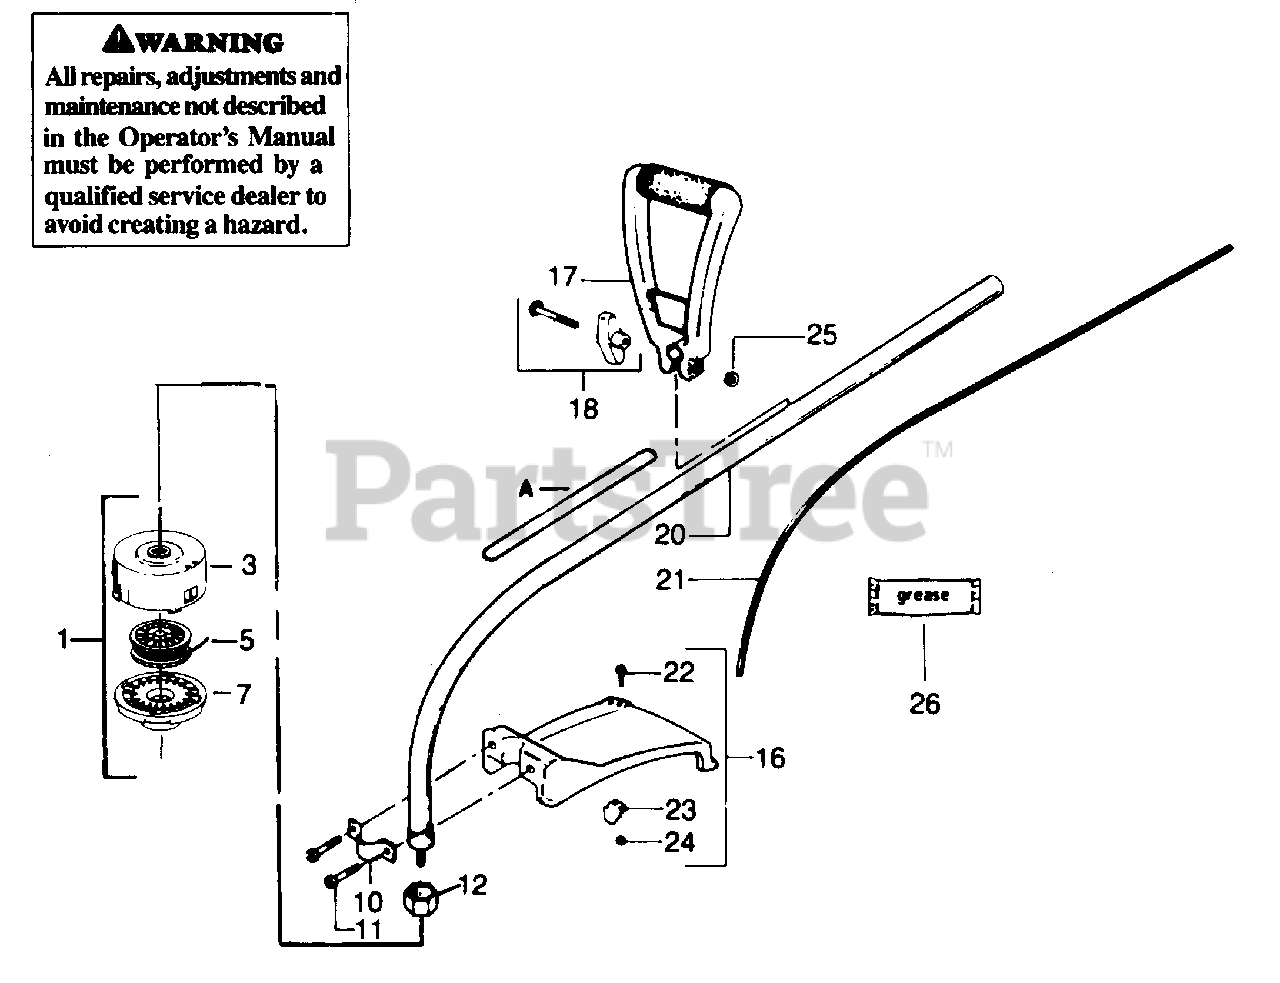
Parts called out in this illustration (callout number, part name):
1	Cutting Head Assembly
3	Hub-Ass'y.
5	Spool w/Line
10	Bracket-Shield
11	Screw-Shield (1/4-10x1-1/8")
12	Dust Cup
16	Shield Kit Assembly (Inc.11,22,23,24)
17	Assist Handle
18	"T" Handle Kit
19	Washer-1/4-Flat
20	Drive Shaft Assembly
21	Flex Shaft Assembly
22	Screw-Line Limiter
23	Line Limiter
24	Nut-Line Limiter
26	Shaft Lubrication
A	Decal-Safety Label
